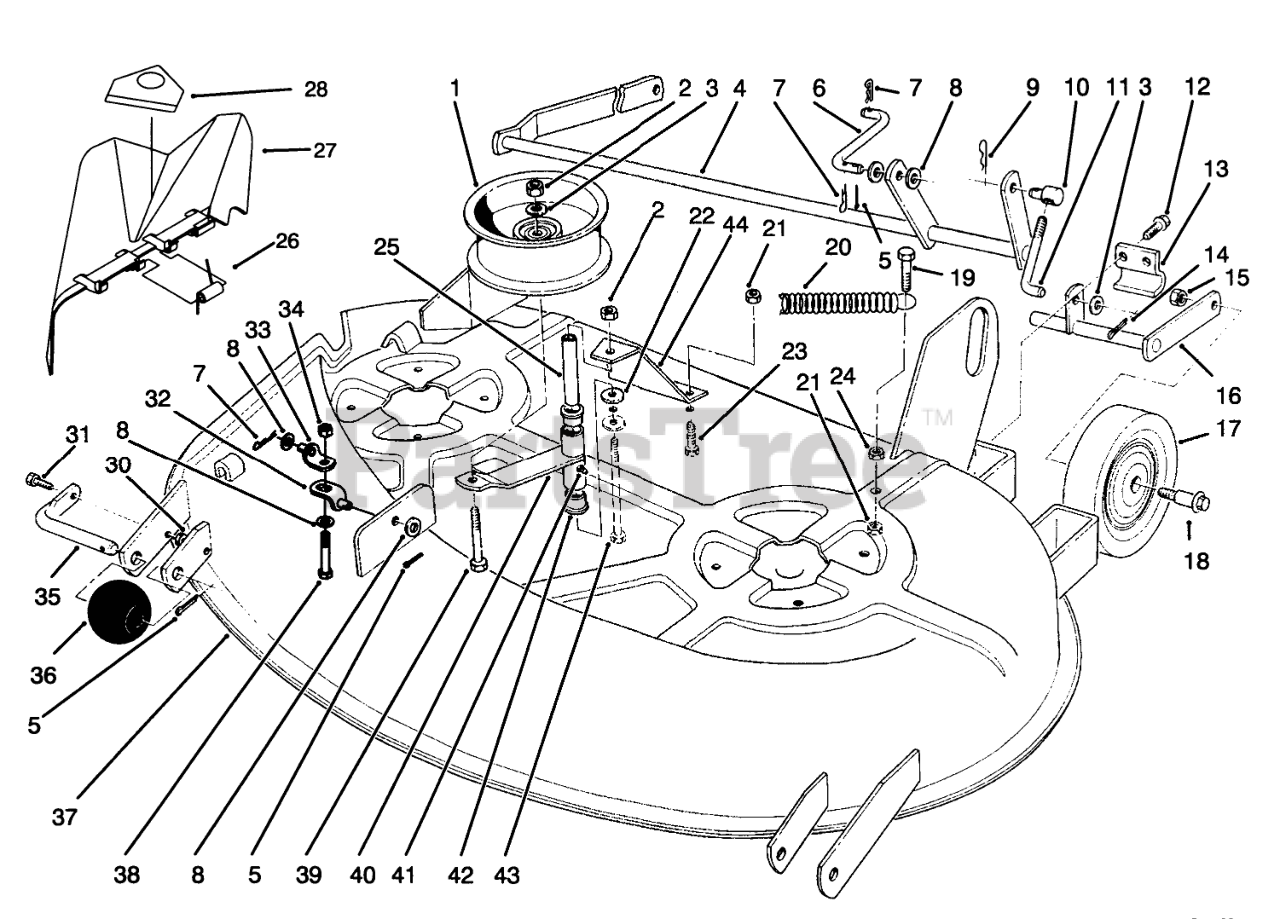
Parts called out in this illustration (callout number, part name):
1	PULLEY-IDLER
2	NUT-LOCK, NI
3	WASHER-FLAT
4	SHAFT-RH
5	PIN-COTTER
6	LINK-REAR
7	Hairpin
8	WASHER-FLAT
9	Hairpin
10	TRUNNION
11	ROD-LIFT
12	Bolt
14	PIN-COTTER
15	NUT-HEX
16	SHAFT-LH
17	WHEEL
18	BOLT-SHOULDER
19	SCREW-HH
20	SPRING-EXTENSION
21	NUT-LOCK, NI
22	WASHER
23	SCREW-HH
24	NUT-HEX
25	SPACER
26	SPRING
27	DEFLECTOR ASM
28	DECAL-DANGER
30	NUT-LOCK, NI
31	SCREW-HH
32	BRACKET-LIFT, LOWER
33	BRACKET-LIFT, UPPER
34	NUT-JAM
35	SHAFT-ROLLER
36	ROLLER
37	Deck/Safety Decal Assy.(Incl. Items 12,& 22, pg. 3)
38	SCREW-HH
39	SCREW-HH
40	WLDMT-IDLER ARM (BLACK)
41	FITTING-GREASE
42	BUSHING
43	SCREW-HH
